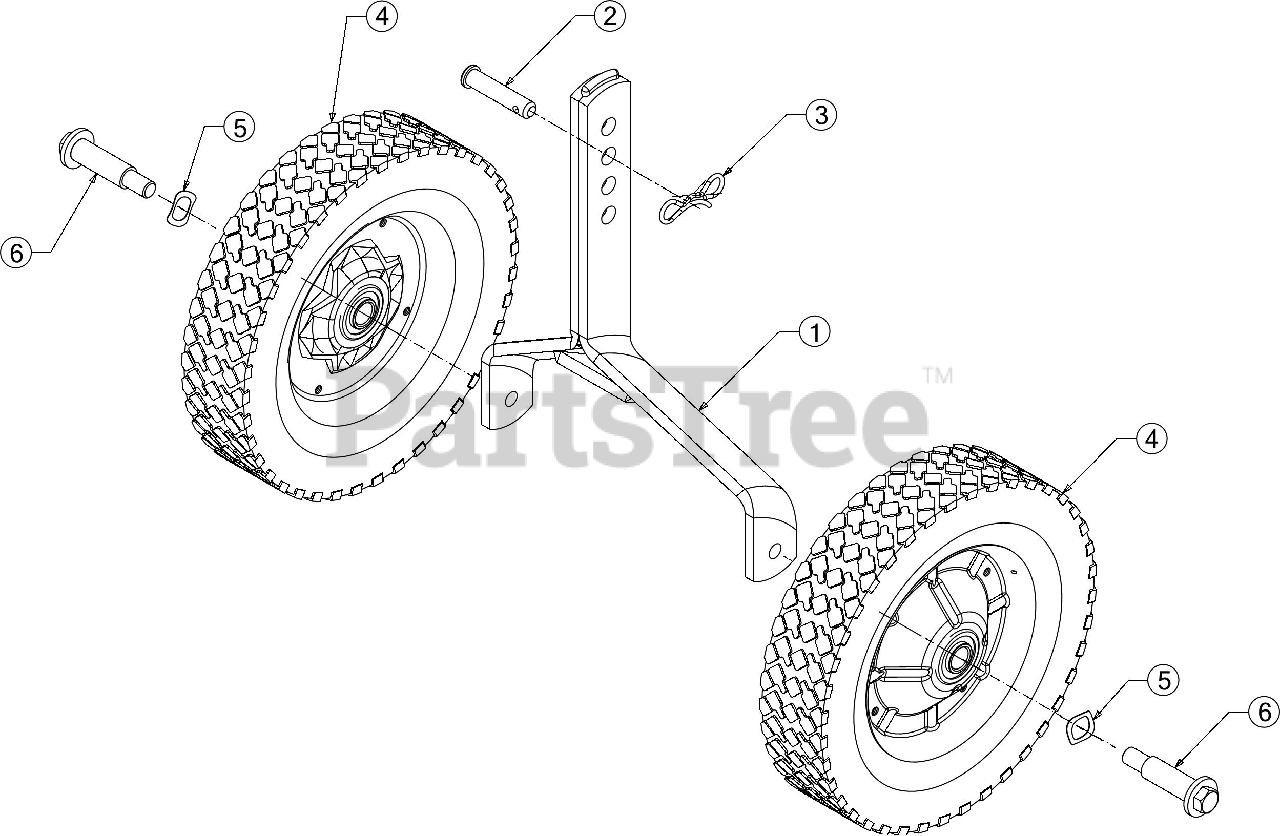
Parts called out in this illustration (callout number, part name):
1	WHEEL BRACKET ASSEMBLY
2	CLEVIS PIN .375 x .1.75
3	PIN:COTTER
4	WHEEL ASSEMBLY W/TIRE (OYSTER GRAY)
5	WAVE WASHER
6	SHOULDER SCREW .496X1.44 3/8-16
